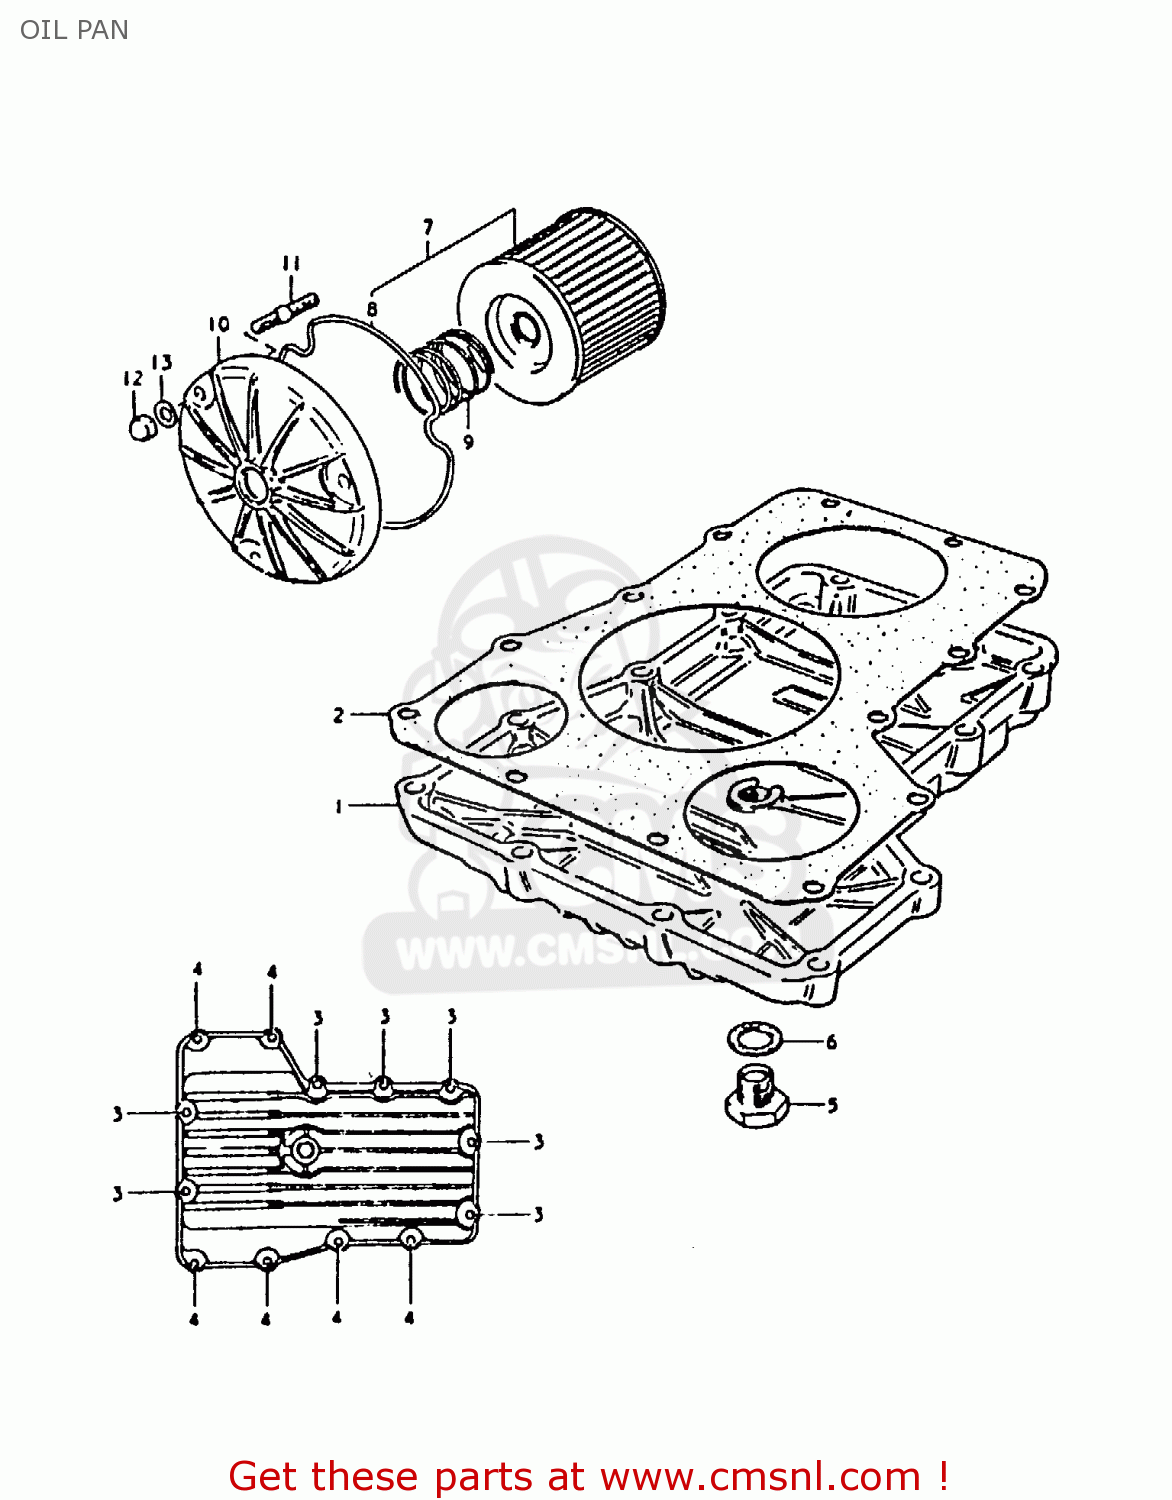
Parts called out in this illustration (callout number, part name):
1	PAN,OIL
2	GASKET,OIL PAN (MCA)
3	BOLT
4	BOLT
5	PLUG
6	GASKET(14X19.2X2) (NAS)
7	ENGINE OIL FILTER SET
8	O RING,OIL FILTER CHAMBER CAP
9	SPRING
10	CAP,OIL FILTER
11	STUD 6X20
12	NUT
13	WASHER
